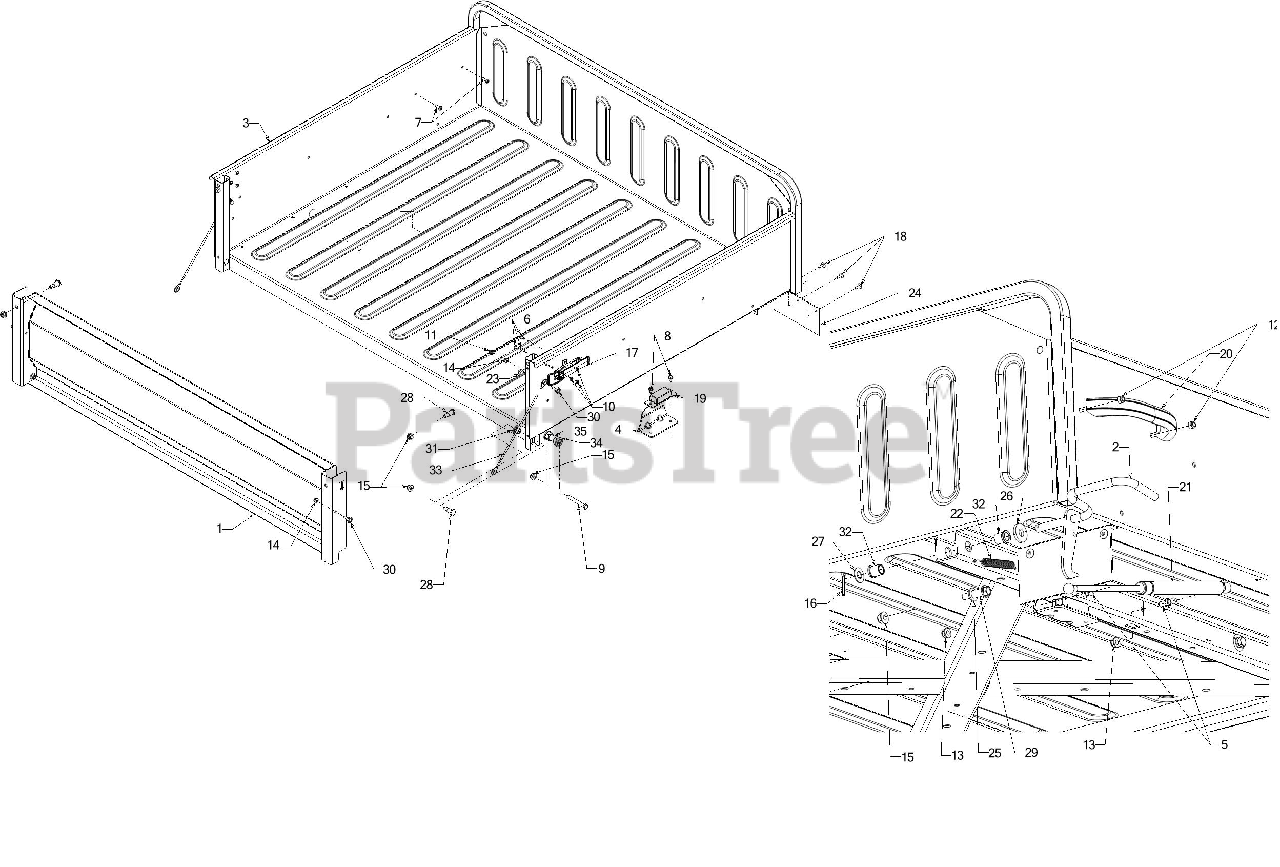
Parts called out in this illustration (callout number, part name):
1	UV TAILGATE ASSEMBLY
2	LEVER ASSEMBLY
3	BED UV BOX ASSEMBLY
4	BED GUIDE BRACKET
5	BALL STUD 5/16-18
6	SCREW #10-24 x .500
7	SCREW 1/4-20X.75
8	SCREW 1/4-20X.625
9	SCREW 3/8-16 x 2.75 GR5
10	LOCK NUT 10-24
12	NYLON LOCK NUT
13	FLANGE LOCK NUT 5/16-18
14	FLANGE LOCK NUT
16	COTTER PIN-5/32 DIA
19	SUSPENSION BUMPER
20	GRAB HANDLE
22	EXTENSION SPRING
23	BUMPER, .62 DIA x .3
25	FLAT WASHER .385X.870X.090
26	FLAT WASHER .531 x 1.25 x .181
27	FLAT WASHER .510X1.000X.060
28	SHOULDER SCREW .500 DIA x .685
29	SHOULDER SCREW .50X.925
30	SHOULDER SCREW .37
31	HEX FLANGE BEARING .506 x .590
32	FLANGE BEARING
33	LANYARD CABLE
34	FLANGE BEARING
35	SPACER:.390 ID x .625OD x 2.03
